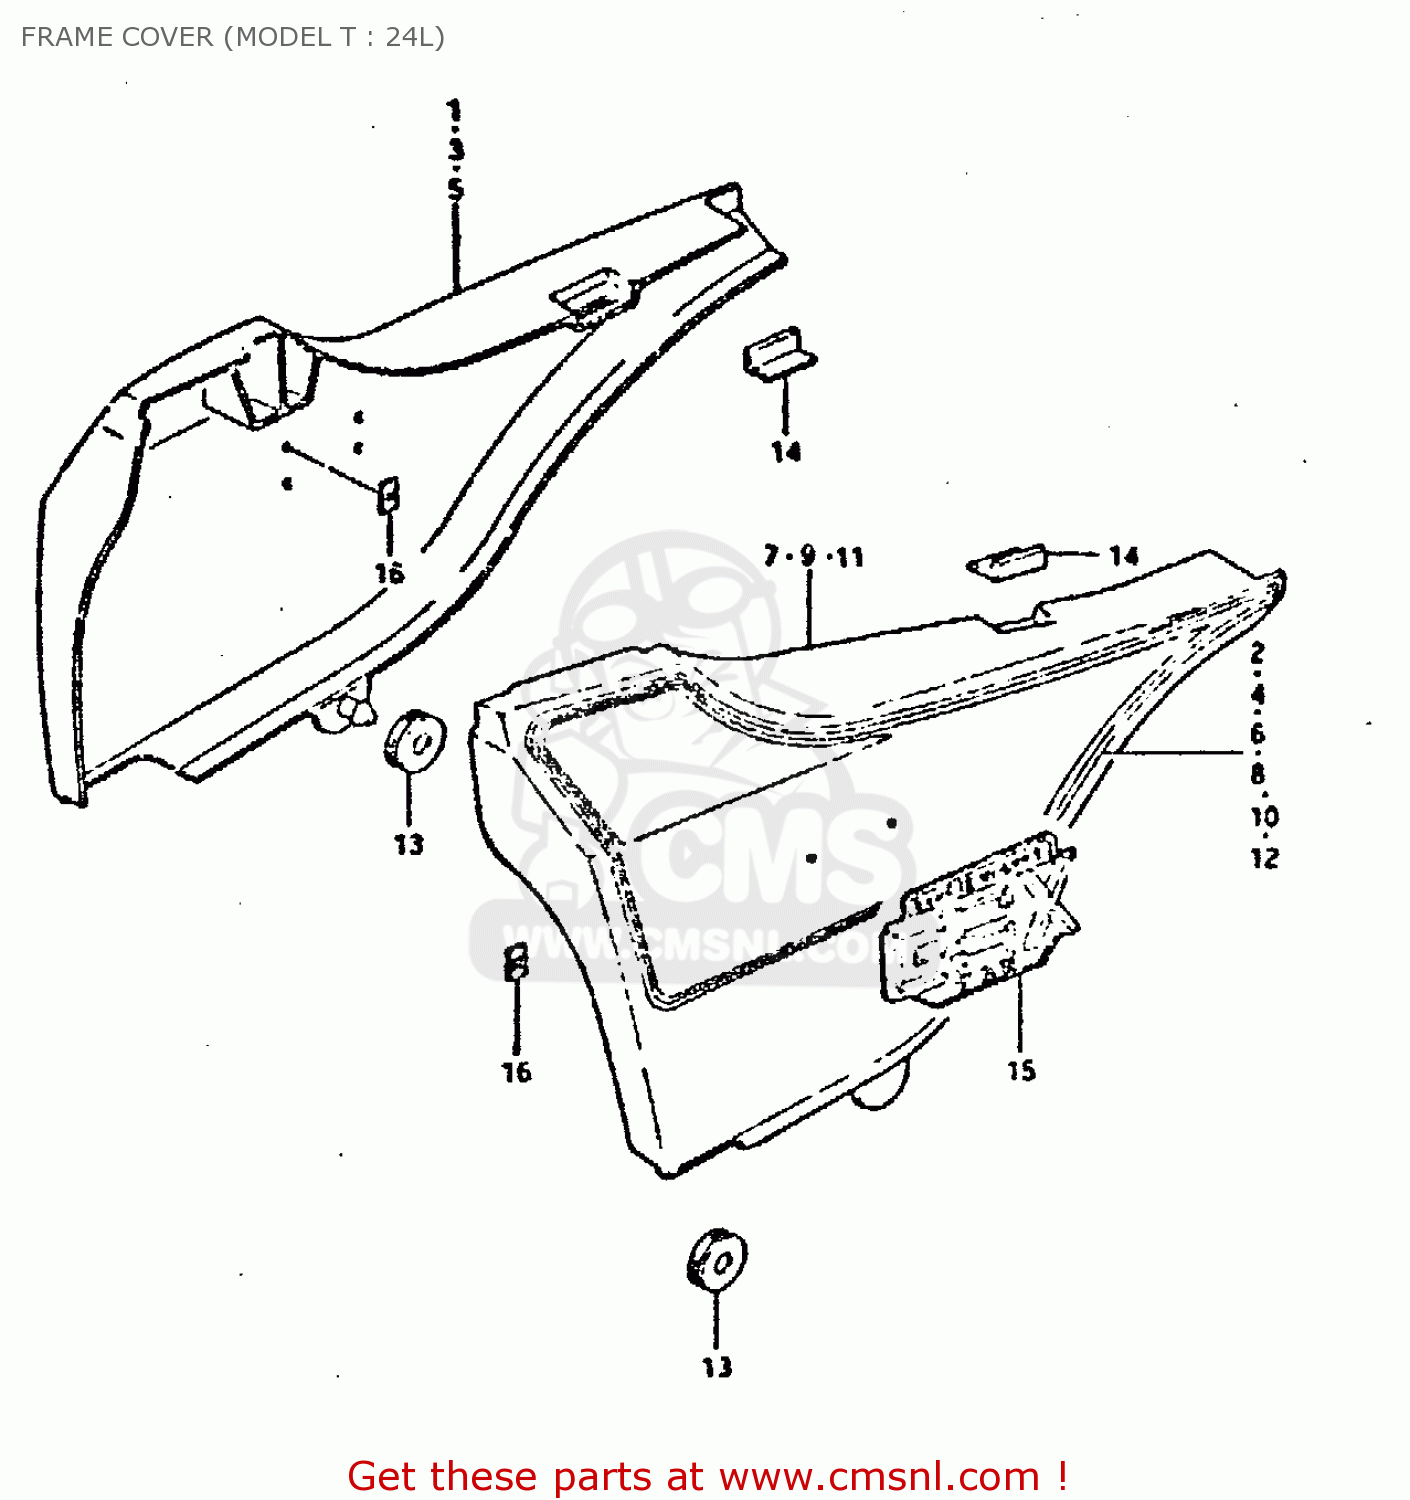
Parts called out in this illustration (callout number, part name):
1	COVER, FRAME RH (BLACK)
2	TAPE, RH
3	COVER, FRAME RH (RED)
4	TAPE, RH
5	COVER, FRAME RH (BLUE)
6	TAPE, RH
7	COVER, FRAME LH (BLACK)
8	TAPE, LH
9	COVER, FRAME LH (RED)
10	TAPE, LH
11	COVER, FRAME LH (BLUE)
12	TAPE, LH
13	CUSHION
14	CUSHION,FRAME COVER
15	EMBLEM,FRAME COVER
16	NUT
